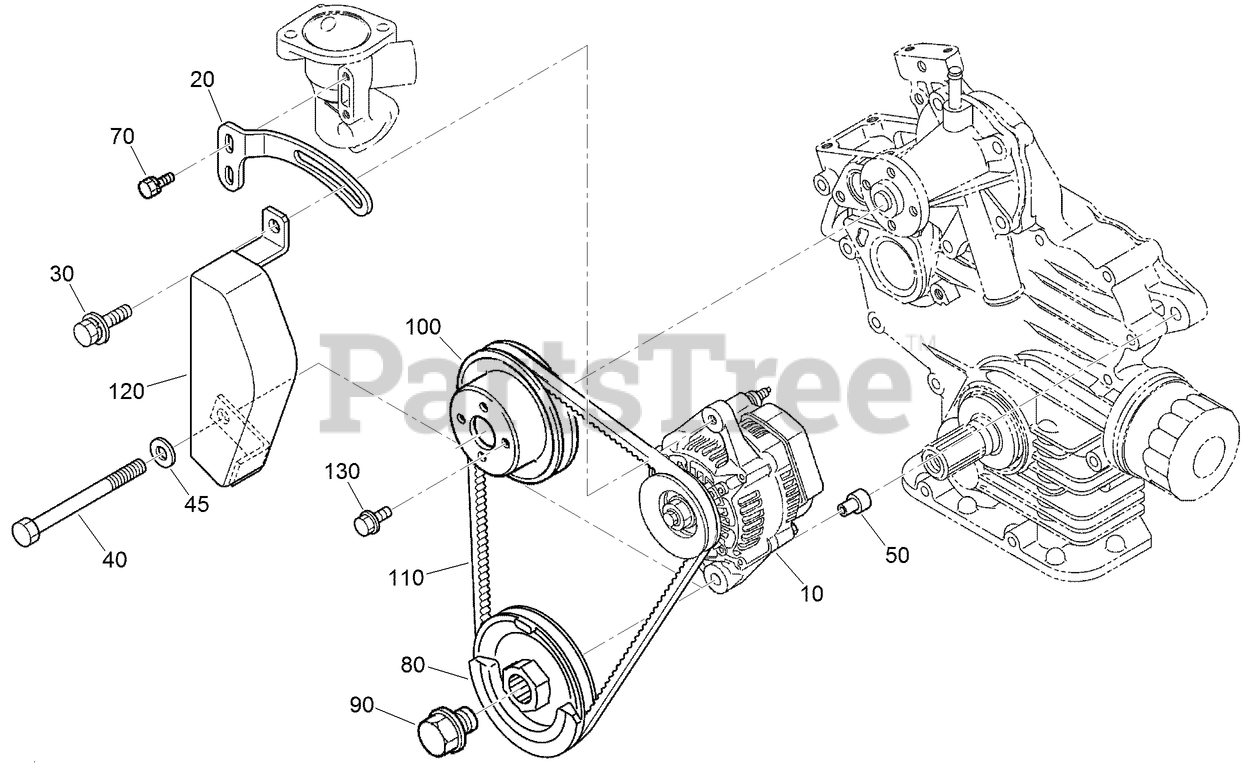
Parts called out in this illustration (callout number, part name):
20	STAY-ALTERNATOR
30	BOLT-SEMS
45	WASHER-PLAIN
50	COLLAR
80	PULLEY-DRIVE, FAN
100	PULLEY-FAN
110	BELT-V
130	BOLT-FLANGE
